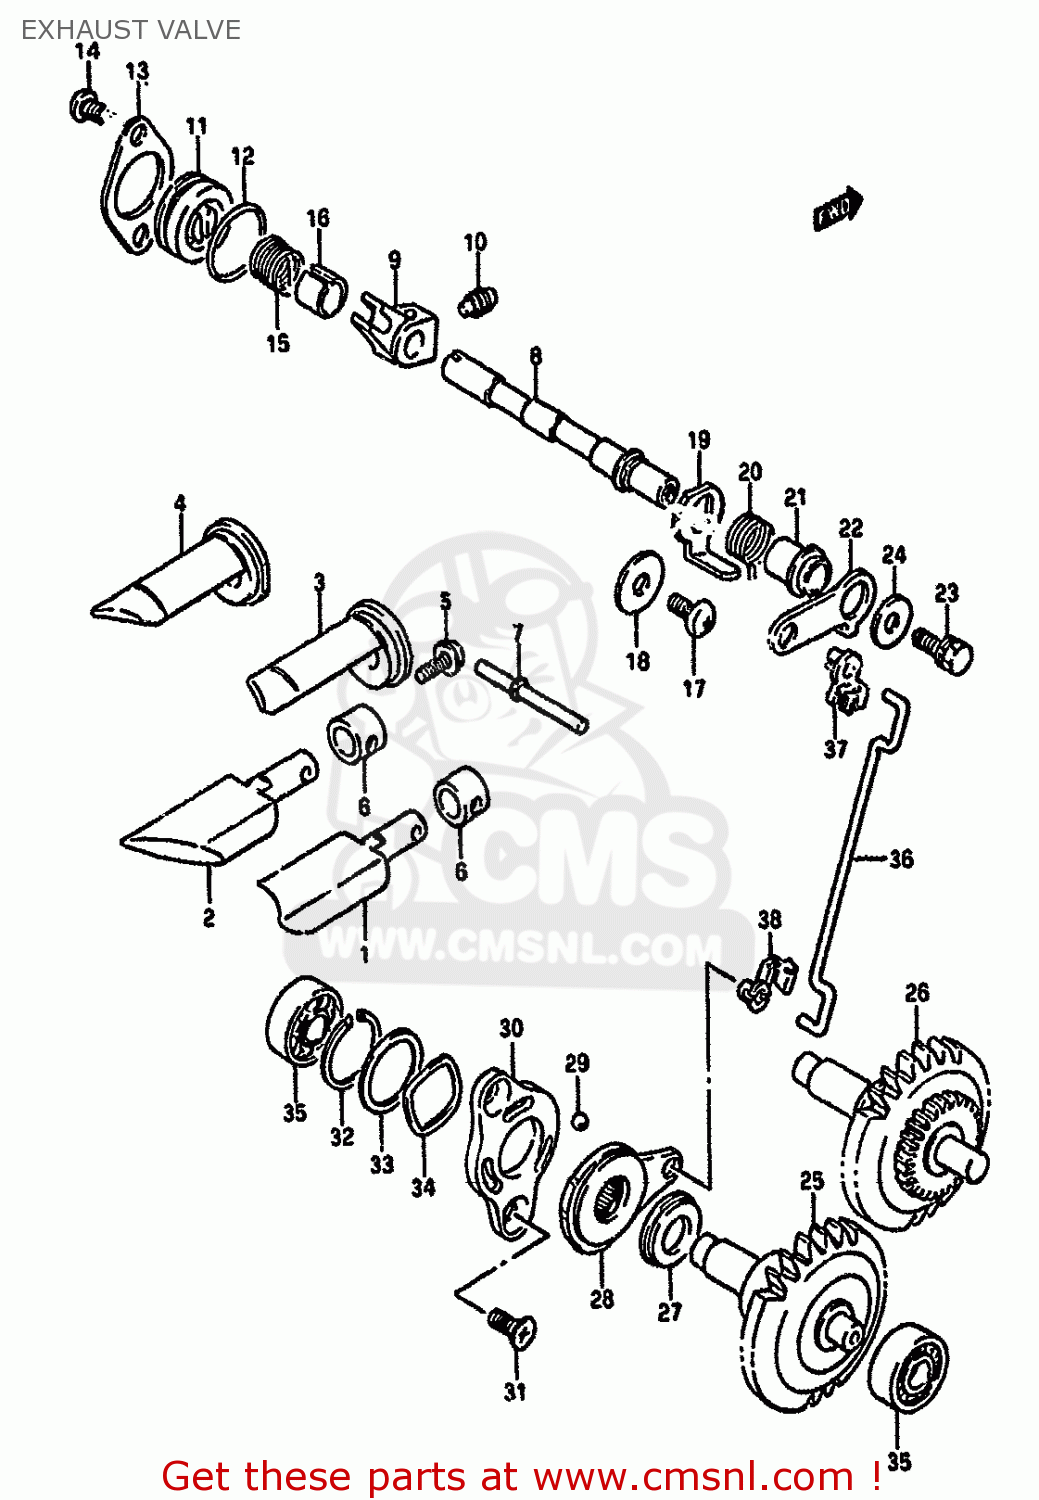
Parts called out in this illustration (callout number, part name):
1	VALVE,EXHAUST,R
2	VALVE,EXHAUST,L
3	GUIDE,EXHAUST VALVE,R
4	GUIDE,EXHAUST VALVE,L
5	SCREW
6	HOLDER,EXHAUST VALVE
7	PIN,EXHAUST VALVE 48.5MM
8	SHAFT,EXHAUST VALVE
9	ARM,EXHAUST VALVE SHAFT
10	SCREW
11	CAP,EXHAUST VALVE
12	O RING(D:1.9,ID:22.6)
13	RETAINER,EXHAUST VALVE
14	SCREW
15	SPRING
16	SPACER,EXHAUST VALVE SPRING
17	BOLT
18	WASHER
19	LEVER,EXHAUST VALVE NO
20	SPRING
21	SPACER,EXHAUST VALVE
22	LEVER,EXHAUST VALVE NO
23	BOLT
24	WASHER (5.5X16X1.2)
25	GOVERNOR ASSEMBLY,EXHAUST
26	GOVERNOR ASSY,EXHAUST VALVE
27	BEARING(10X22X2.8)
28	ACTUATOR,EXHAUST VALVE
29	BALL
30	STARTER,EXHAUST VALVE ACTUATOR
31	SCREW(5X10)
32	CIRCLIP
33	SHIM(19.1X25X0.3)
34	WASHER
35	BEARING(8X22X7)
36	ROD,EXHAUST VALVE
37	BUSH,EXHAUST VALVE ROD NO.1
38	BUSH,EXHAUST VALVE ROD NO.2
